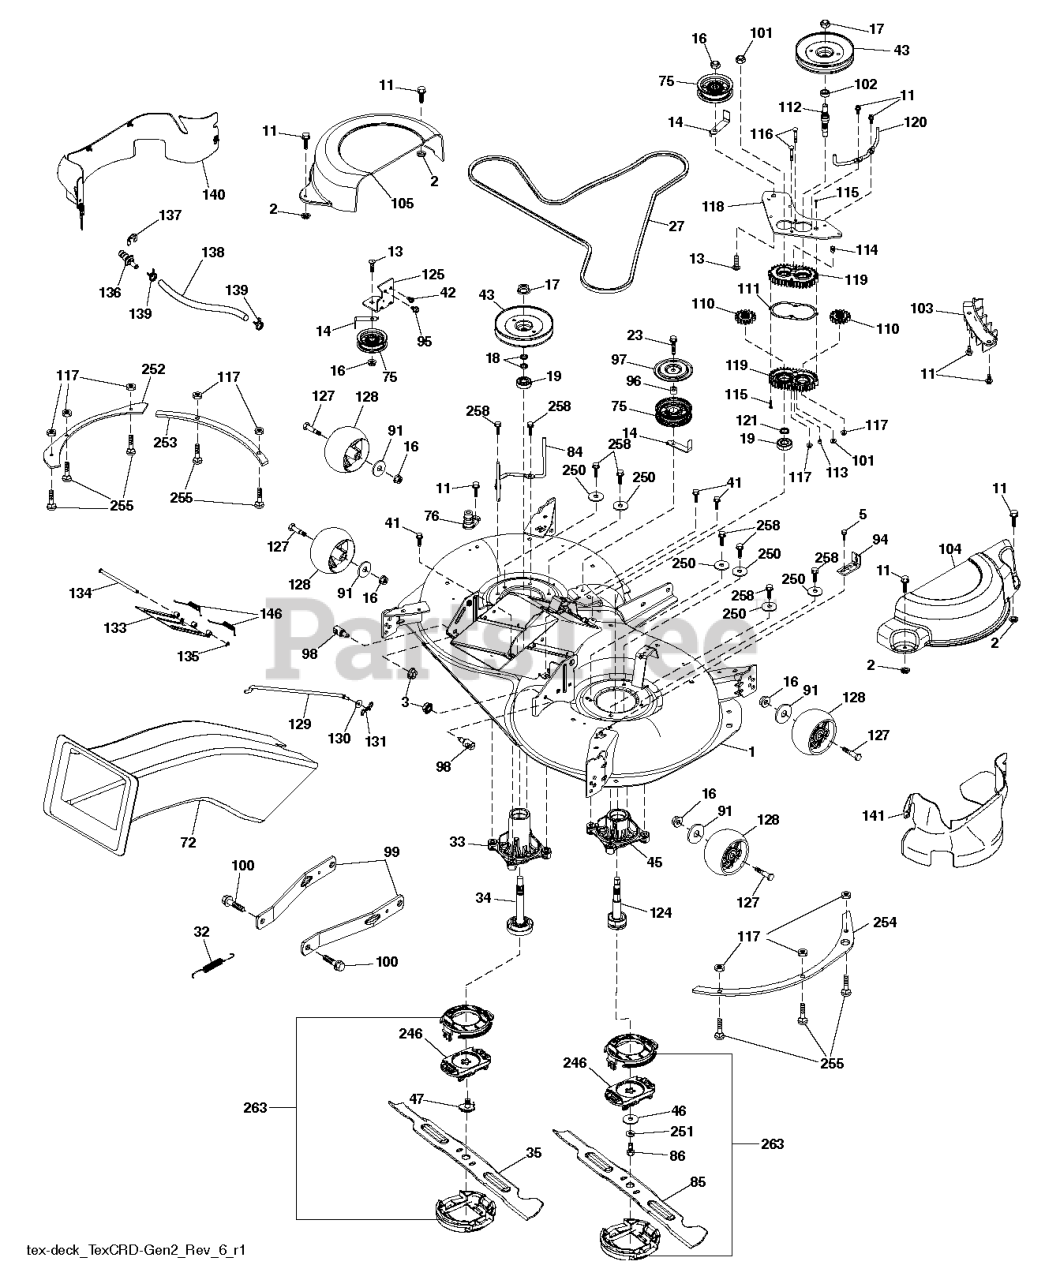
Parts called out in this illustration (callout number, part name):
1	DECK.SVC.WLDT.97EL.TCRD.EZ.498
2	PALNUT 1/4
3	NUT LOCK HEX FLANGE 5/16-18
5	BOLT.5/16HEX.WHS.HD
11	SCREW.1/4-20X5/8
13	BOLT.3/8-16X1.50
14	KEEPER, BELT IDLER
16	NUT LOCK FLG 3/8-16 UNC
17	NUT.FLANGE.LOCK.TOP
18	WASHER.SPACER.MANDREL
23	SCREW LT
27	BELT 97CM ELECTRIC
32	SPRING 107CM & 97CM ELECTRIC D
33	RP.HOUSG.MAND.REV.TALL.N/GRS
34	RP.SAFT ASM.REV.TALL.N/GREASE
35	BLADE.REVOLUTION.97CM.LHS
41	BOLT.HEX.WASHR.HED.313-18X1.19
42	SCREW
43	PULLEY.MANDREL.5.0.PD.38"
45	RP HOUSING.MANDREL.REV.REVS.
46	3/8 FLAT WASHER
47	SCREW.SEMS.7/16-20X1.HEX.HEAD
72	RP.CHUTE 107/97 TEX GENII
75	FLAT IDLER PULLEY
76	1/2" BARB.DECK.WASHOUT.PORT
84	BELT KEEPER.MANDREL.38"COATED
85	BLADE.REVOLUTION.97CM.RHS
86	BOLT.3/8-24X1.25GR8. LHTHRD
91	WASHER
94	BRKT.CLUTCH.CABLE
95	SCREW, 3/8-16X3/4
96	SPACER
97	PROTECTOR
98	STUD.FASTNER.W/ANTI-ROTATE
99	ARM.SUSPENSION.MOWER.R
100	BOLT.SHOULDER
101	NUT.CROWNLOCK.9/16 -18.UNC
102	SPACER BEARING
103	GUARD GUARD FRONT VENT
104	97.CRD.RH.MANDREL.COVER
105	MANDREL MANDREL COVER LH
110	CRD.SPUR.GEAR
111	GASKET GASKET GEARCASE
112	SHAFT SHAFT. CRD GEARCASE ADAP
113	PLUG PLUG OIL
114	VALVE VALVE RELIEF
115	SCREW
116	BOLT.CARIGE.SS.1/4-20X1.75GR5
117	NUT T
118	ARM ARM CLUTCHING
119	GEARCASE GEARCASE SUBASM
120	BRACKET KEEPER BELT RH
121	WASHER WASHER
124	SUB.ASM.REVERSE.THREAD.REV
125	BRACKET
127	BOLT.SHOULDER.3/8-16X3-5/8.
128	RP WHEEL. GUAGE RALLY
129	ROD ROD. SWAY CRD GEN II
130	WASHER
131	PIN.COTTER.5/16.BOW TI
133	DOOR
134	PIN PIN.HINGE
135	E-RING.5/16"
136	PLUG WASHOUT PORT HOOKUP
138	HOSE.3/8ID.BULK.12"
139	HOSE.3/8.CLAMP (2 2)
140	GUARD
141	GUARD SUBASM.TEX CRD 97CM RH F
146	SPRING SPRING: EZ MULCH DOOR
246	HOLDER.BLADE.REVOLUTION
251	LOCKWASHER
252	PLATE.REINFORCEMENT.X431
253	PLATE.REINFORCEMENT.LHS.X431
254	PLATE.REINFORCEMENT.LHS.X431
255	RHSNB, 1/4-20 X 1, GR5
258	BOLT.HEX.WASHR.HED.313-18X1.19
263	CAP.REVOLUTION ASM
